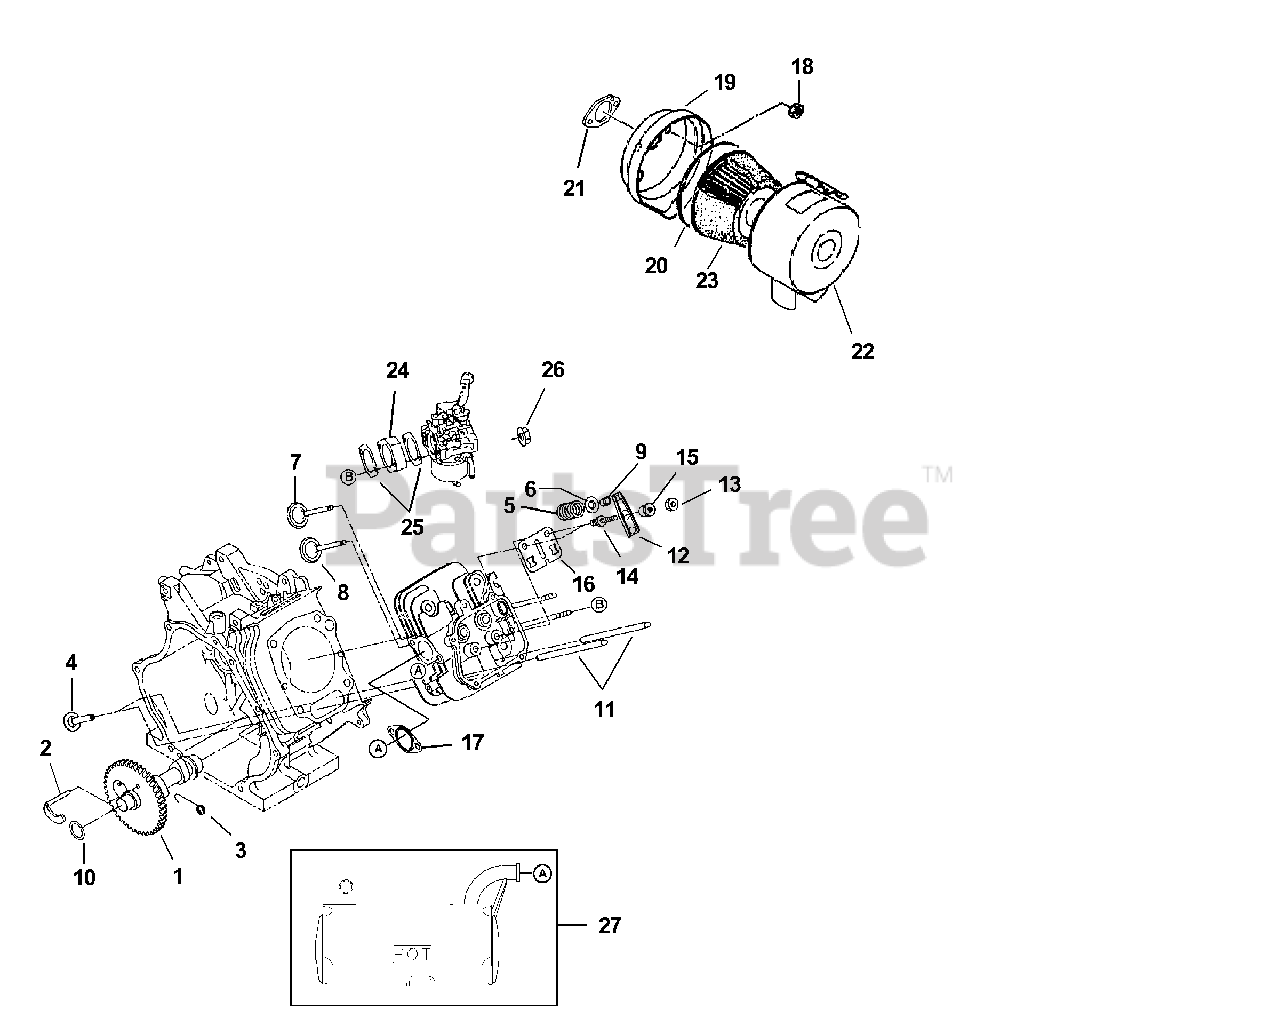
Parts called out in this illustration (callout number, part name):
1	Camshaft
2	Release lever cp
3	Return spring
5	Valve spring
6	Spring retainer
7	Intake valve
8	Exhaust valve
9	Collet, valve
10	Spacer T=0.6
11	Push rod
12	Rocker arm
13	Nut
14	Bolt, pivot
16	Guide plate
17	Gasket, exhaust
19	Cleaner base cp
22	Cleaner cover
23	Element, Air Cleaner
24	Insulator
25	Gasket, insulator
26	Flange nut
